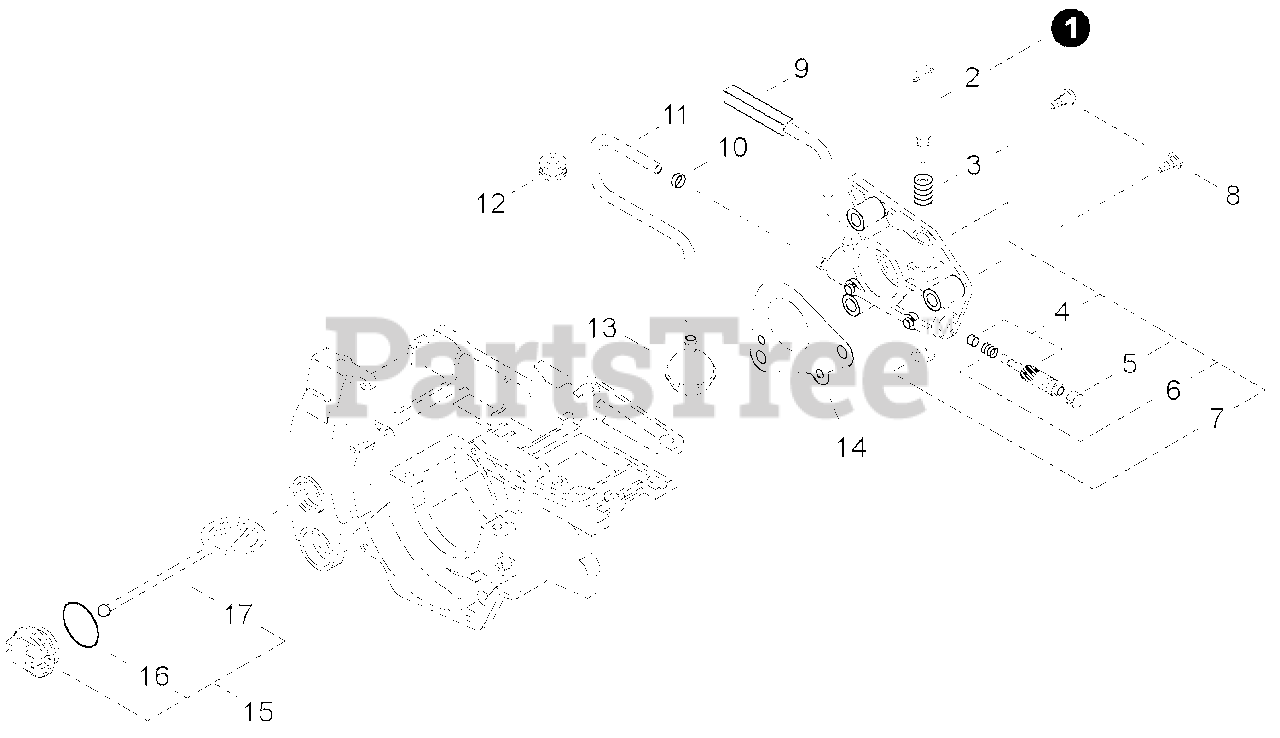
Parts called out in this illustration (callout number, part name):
1	AUTO-OILER ASSY
2	SCREW, ADJUST
4	PLUNGER
5	CAP, OIL PUMP
7	RING, RETAINING
8	SCREW - 4X16
9	TUBE, OIL OUTLET
10	CLIP - 6.5
11	PIPE - OIL
13	FILTER, OIL
14	SEAL, DUST
15	CAP ASSY - ORANGE
16	O-RING - 25
17	CONNECTOR, CAP
